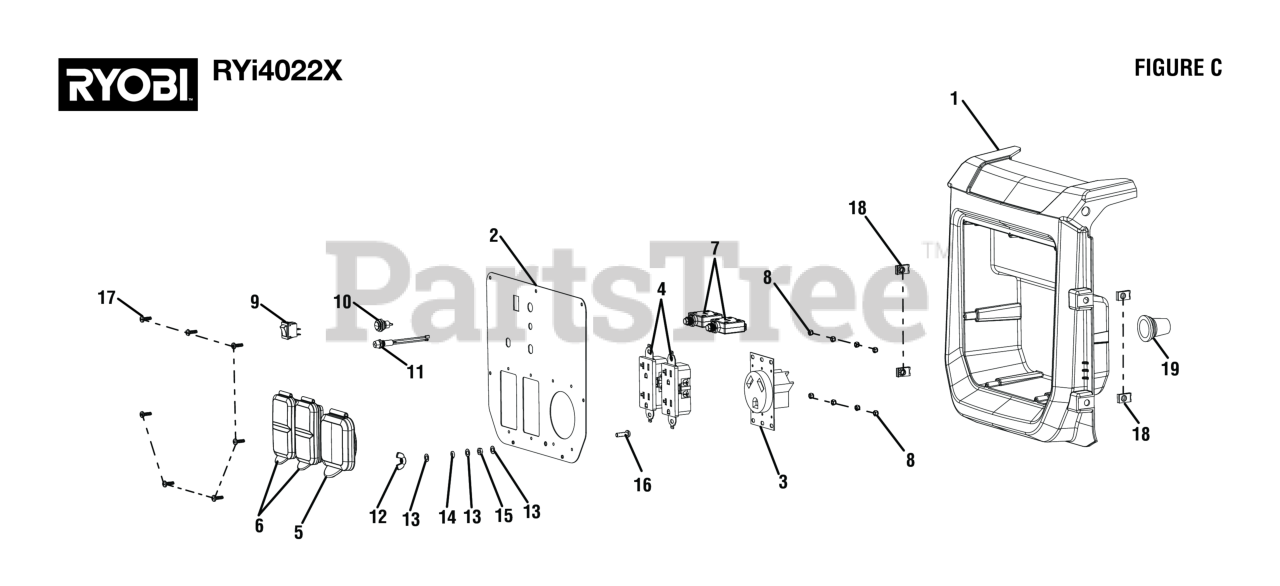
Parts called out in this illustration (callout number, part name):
1	Electrical Panel Housing
2	Control Panel
3	Twist Lock Receptacle (120 Volt, 30 Amp)
4	120 Volt Duplex Receptacle (BM903611)
5	Outlet Cover
6	120 Volt Receptacle Rain Cover
7	Circuit Breaker (20 Amp)
8	Lock Nut (M4)
9	Auto Idle Switch
10	Reset Button
11	Indicator (Red LED 3.3V-4mA)
12	Wing Nut (M5)
13	Flat Washer (OD10 x ID5.3 x 0.5t)
14	Lock Washer (OD9 x ID5 x 1.3t)
15	Hex Nut (M5)
16	Screw (M5 x 16 mm, Phillips Pan Hd.)
17	Screw (M4.2 x 12mm, Phillips Button Hd.)
18	U-Clip (M6)
19	Wiring Rubber Boot
